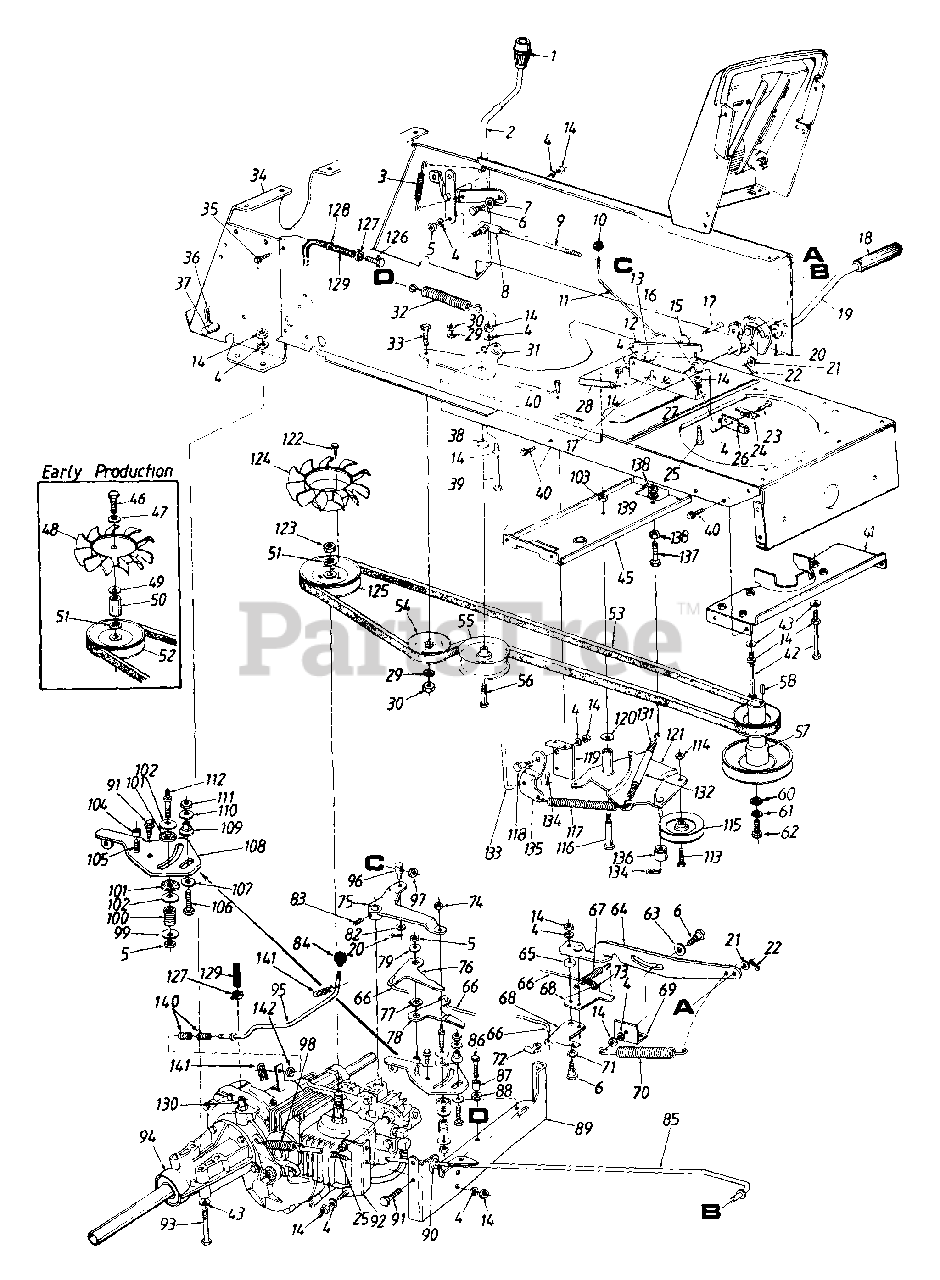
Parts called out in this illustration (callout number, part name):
1	Shift Knob
2	Speed Control Lever Ass'y.
3	Ext. Spring 2.75" Lg.
4	L-Wash. 5/16" I.D.
5	Hex Nut 5/16-24 Thd.
6	Shld. Bolt .437" Dia. x .268"
7	Spr. Wash. .445" I.D. x .75" O.D.
8	Ball Joint 5/16-24 Thd.
9	Speed Selector Adjusting Rod
10	Ball Knob
11	Brake Lockout Rod
14	Hex Nut 5/16-18 Thd.
15	Shld. Spacer .27" Lg.
16	Hex Flange Bearing
17	Hex Bolt 5/16-18 x 1.25" Lg.
18	Foot Pad
21	Fl-Wash. .34" I.D. x .68" O.D.
22	Cotter Pin 1/8" Dia. x 1" Lg.
23	Hex B-Tap Scr. #10 x .62" Lg.
24	Switch Plate
25	Hex Bolt 5/16-18 x .75" Lg.
26	Safety Switch (Clutch)
27	Clutch Ass'y. Mtg. Brkt.
28	Ext. Spring 2.51" Lg.
29	L-Wash. 3/8" I.D.
30	Hex Nut 3/8-16 Thd.
31	Idler Brkt.
32	Ext. Spring 4.75" Lg.
33	Hex Bolt 3/8-16 x 1.5" Lg.
36	Hitch Pin
37	Hitch Rod
38	Shld. Spacer .625" I.D.
39	Hex Bolt 5/16-18 x 2.75" Lg.
40	Hex Wash. Hd. TT-Tap Scr. 1/4-20 x .5" Lg.
41	Belt Guard Brkt.
42	Hex Bolt 5/16-18 x 5.25" Lg.
43	Bell-Wash..345" I.D. x .88" O.D.
45	Deck Idler Support Brkt.
46	Hex Cap Bolt 9/16-18 x .5" Lg.
47	Bell-Wash..567" I.D. x 1.125" O.D.
49	Fl-Wash. 9/16" I.D. x 1.75" O.D.
50	Fan Adapter Nut 9/16-18 Thd.
51	Int. L-Wash. 9/16" I.D.
52	Input Pulley
53	"V"-Belt
54	Idler Pulley
55	Fl-Idler Pulley
56	Hex Bolt 3/8-16 x 2" Lg. (Gr. 8)
57	Engine Pulley
58	Sq.-Key 1/4" x 1.5" Lg.
60	Fl-Wash. .44" I.D. x 1.25"
61	L-Wash. 7/16" I.D.
62	Hex Cap Bolt 7/16-20 x 1.5" Lg.
63	Fl-Wash. .531" I.D. x 1.25" O.D.
64	Neutral Return Link Ass'y.
65	Fl-Wash .344" I.D. x 1.12" O.D. (Hdn.)
66	Connecting Rod
67	Ext. Spring 2.5" Lg.
68	Balancer Brkt.
69	Bracket
70	Ext Spring 3.94" Lg.
71	Spr.-Wash .445" I D x .75" O.D.
72	Rod End Clevis Clip -- R.H.
73	Rod End Clevis Clip -- L.H.
74	Hex Ins. L-Nut 3/8-24 Thd.
75	Pintle Bracket Ass'y.
76	Flat Scissors
77	Spr Wash. .625" I.D. x .885" O.D.
78	Offset Scissors
79	Fl-Wash. .344" I.D. x 1" O.D. (Hdn.)
82	Fl-Wash. .406" I.D. x .75" O.D
83	Hex Socket Set Screw
84	Ball Knob
85	Brake Rod Ass'y
86	Hex Wash Hd. Scr 1/4-20 x 1.5" Lg
87	Spacer 39" Lg.
88	Hex Nut 1/4-20 Thd. (Gr. 5)
91	Hex Wash Hd. TT-Tap Scr. 5/16-18 x .62" lg
94	Transaxle
95	Bypass Rod
96	Ferrule 3/8-24 Thd.
97	Hex Jam Nut 3/8-24 Thd.
98	Ext. Spring 4.01" Lg.
99	Fl-Wash .312" I.D x .75" O.D
100	Comp. Spring 1.19" Lg.
101	Friction Washer
102	Bell-Wash .40" I.D. x 1.13" O.D.
103	Hex Cent L-Nut 3/8-16 Thd.
104	Spacer
105	Rib Neck Bolt 5/16-18 x .62" Lg.
106	Hex Bolt 1/4-28 x 1" Lg. (Gr. 5)
107	Fl-Wash. .26" I.D. x .72" O.D.
108	Scissors Mtg. Brkt.
109	Centering Gauge Spacer
110	Bell-Wash. 1/4" I.D.
111	Hex Nut 1/4-28 Thd.
112	Friction Disc Stud
113	Hex Bolt 3/8-24 x 1.5" Lg.
114	Hex Cent. L-Nut 3/8-24 Thd.
115	V-Belt Idler
116	Shld. Bolt .498" Dia. x 2.05
117	Ext. Spring 6.12" Lg.
118	Shld. Bolt .437" Dia. x .162"
119	Parking Brake Mtg. Brkt.
120	Bell-Wash. .38" I.D. x .88" O.D.
121	Idler Brkt. Deck Ass'y.
122	Hex Wash. Hd. Tap Scr. #12 x 3/8" Lg.
123	Hex Jam Nut 9/16-18 Thd.
124	Fan
125	Input Pulley
126	Plastic Vent
127	Rubber Grommet
128	Cable Tie
129	Hose 1/2" I.D. x 18" Lg.
130	Hose Fitting
131	Ext. Spring 6.37" Lg.
132	Convoluted Conduit
133	Deck Control Rod
134	Internal Cotter Pin
135	Deck Control Pivot Brkt.
136	Spacer
137	Hex Bolt 1/4-20 x 2" Lg.
138	Hex Nut 1/4-20 Thd.
139	L-Wash 1/4" I.D
140	Comp. Spring 1" Lg.
141	Hairpin Clip
142	Fl-Wash. 1/4" I.D.
